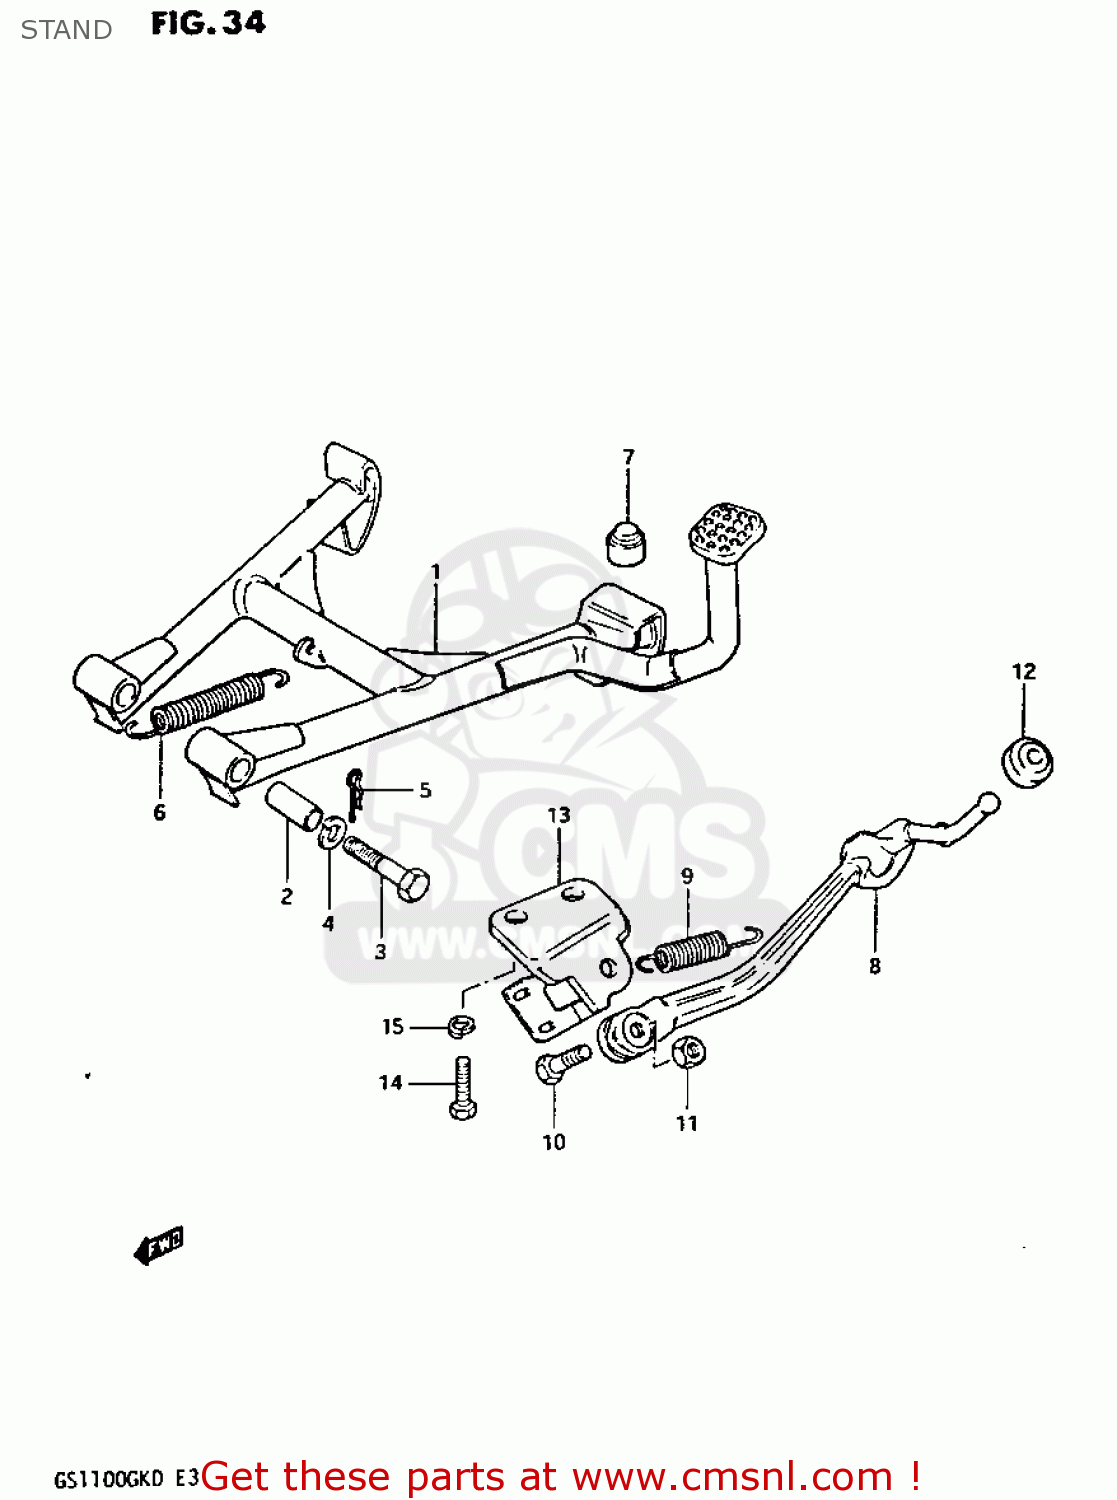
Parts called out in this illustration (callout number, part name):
1	STAND,CENTER
2	SPACER(10X16X38.8)
3	BOLT(10X65)
4	WASHER,LOCK,10
5	CLIP
6	SPRING
7	CUSHION
8	STAND,SIDE
9	SPRING
10	BOLT(10X34)
11	NUT
12	CUSHION
13	BRACKET,SIDE STAND
14	BOLT
15	WASHER,LOCK,10
